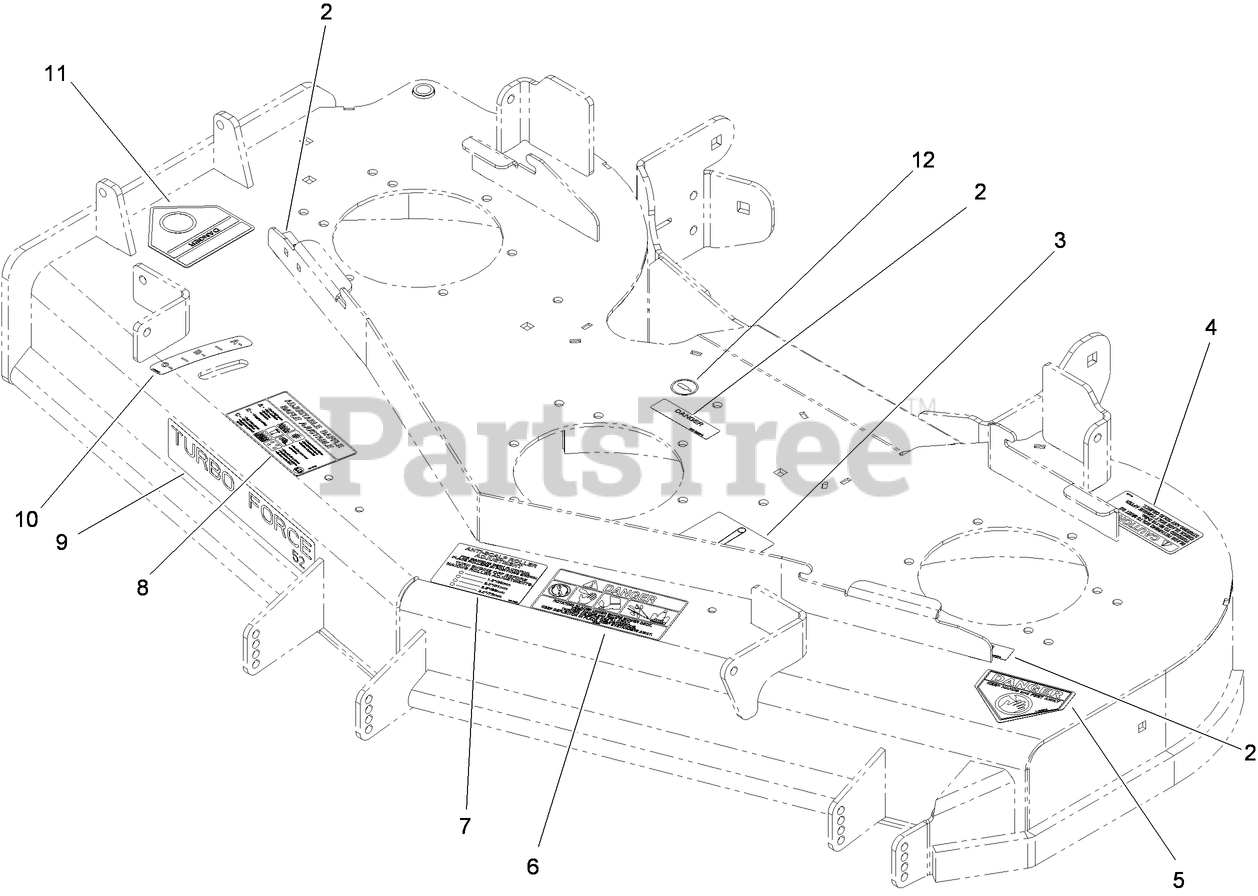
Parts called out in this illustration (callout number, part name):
2	DECAL-COVER, MISSING
3	DECAL-ROUTING, DECK BELT
4	DECAL-TORQUE
5	DECAL-DANGER
6	DECAL-DANGER, THROWN OBJECT
7	DECAL-SCALP, ANTI
8	DECAL-ADJUSTMENT, BAFFLE
10	DECAL-SETTING, BAFFLE
11	DECAL-DANGER
12	DECAL-GREASE
